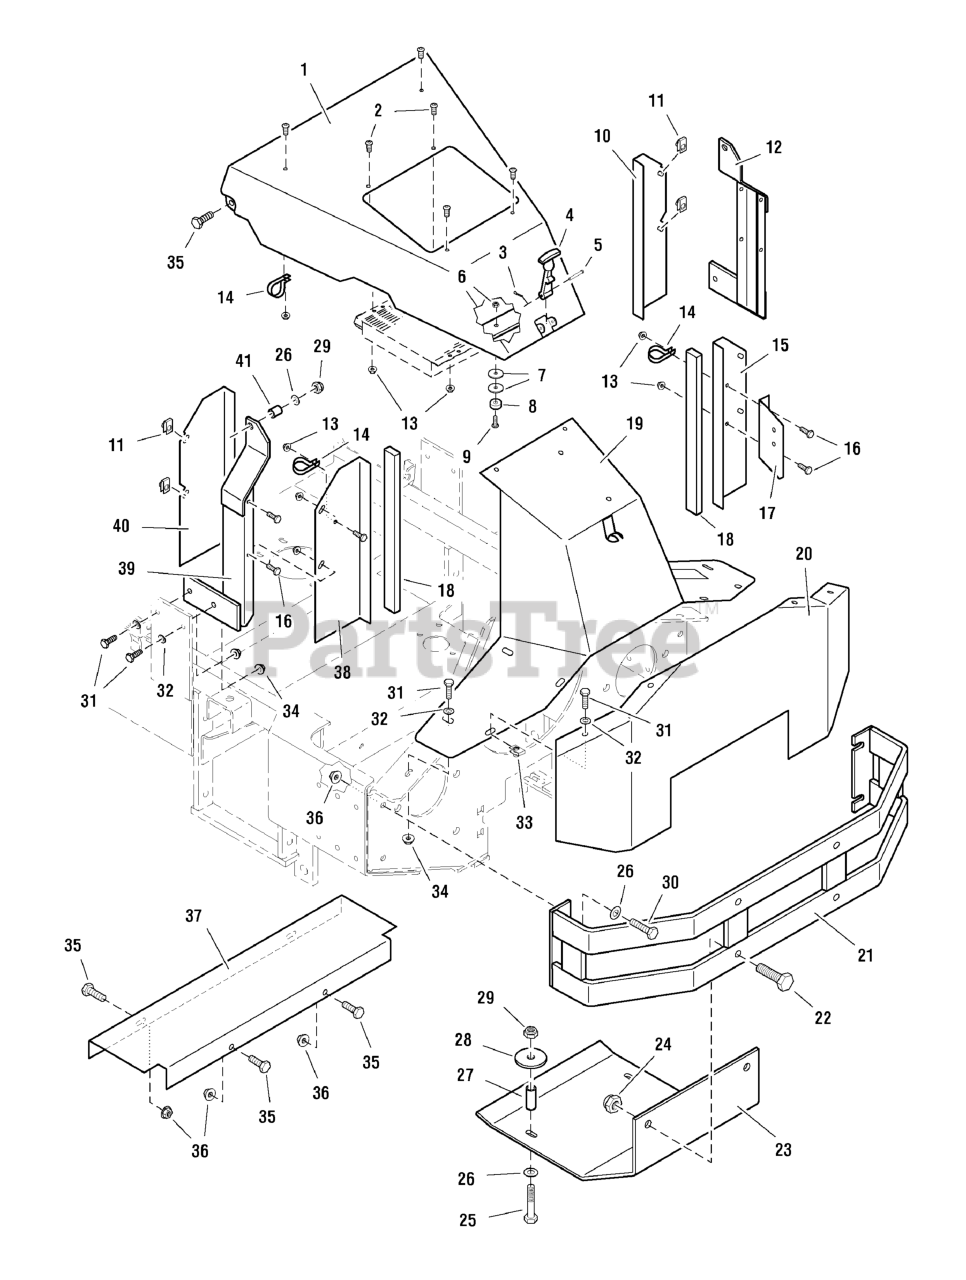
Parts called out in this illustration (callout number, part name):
3	COTTER PIN
4	RUBBER LATCH
5	CLEVIS PIN
6	NUT, #10-24 Hex Nylon Lock
7	WASHER, 1/4" Fender
8	RUBBER BUMPER
9	SCREW, #10-24 x 3/4
10	SHROUD COVER-RH
11	BODY CLIP, 1/4-20
12	HOOD MOUNT CHANNEL-RH
13	NUT, 1/4-20 HEX SERR. FLANGE
14	CLAMP, Vinyl
15	AIR BAFFLE-RH
16	HHCS, 1/4-20 X 0.625, GR5, ZINC/CLEAR
17	OVERFLOW BOTTLE MOUNT
18	FOAM SEAL, 16"
19	REAR HOOD SUPPORT
20	REAR SHIELD
22	BOLT, 1/2-20 X 1-1/2, GD5 CZ
23	SKID SHIELD
24	NUT, Hex, Nylon Lock, 1/2-20
25	BOLT, 3/8-16 X 2-1/2" GD5 CZ
26	WASHER, 3/8 SAE
27	SPACER, .38 x .50 x 1.56
28	WASHER, 3/8 x 1-3/4
29	NUT, 3/8-16 HEX NYLON LOCK
30	BOLT, 3/8-16 X 1-1/4" GD5 CZ
31	BOLT, 5/16-18 X 1 GD5 YZ
32	WASHER, 5/16" SAE
33	BODY CLIP, 5/16-18-7GA MATERIAL
34	NUT, 5/16-18 HEX SERRATED FLANGE (SMALL)
35	BOLT, 3/8-16 X 1" GD5 CZ
36	NUT, 3/8-16 Hex Serrated Flange
37	DEBRIS SHIELD
38	AIR BAFFLE-LH
39	HOOD MOUNT CHANNEL-LH
40	SHROUD COVER-LH
41	SPACER, .38 x .50 x .27
